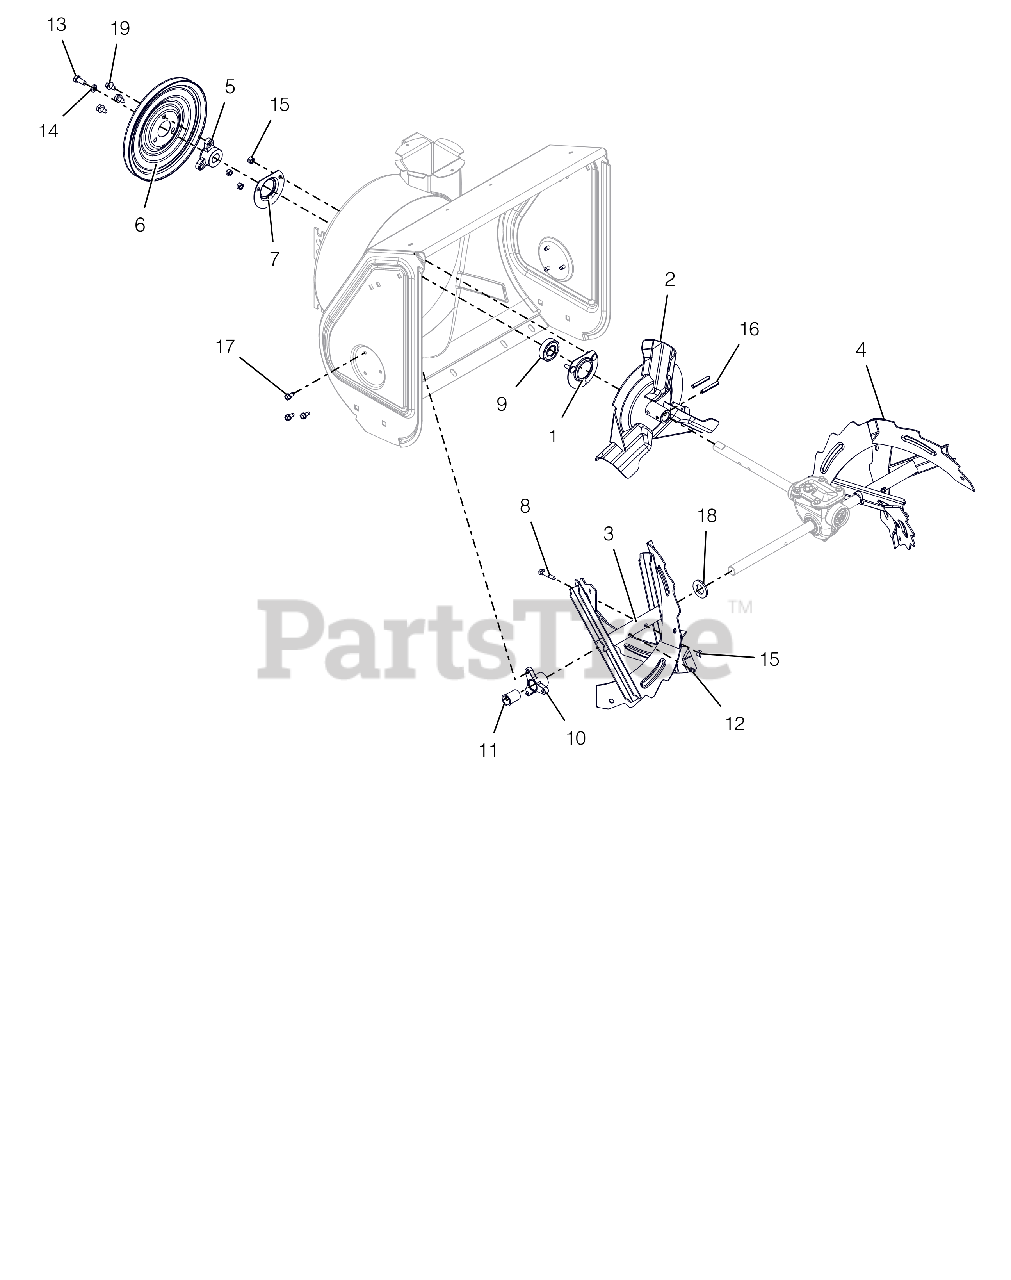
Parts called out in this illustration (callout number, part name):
1	BEARING FLANGE
2	IMPELLER, COMPACT 12" 3-BLADE
3	AUGER, 20" RH, BLK SERR W/ZERK
4	AUGER, LH 20", BLK SERR W/ZERK
5	PULLEY HUB, BOLT-ON D-BORE .75
6	PULLEY,SPIN FORM SINGLE GROOVE
7	BEARING FLANGE
8	SHEAR BOLT
9	BRG-BALL .750X1.750X.50
10	BUSHING, RAKE SHAFT .75"
11	BSHG-FLG SPLIT NYLINER .75"ID
12	ZERK,FITTING .25X.125 DRIVE IN
13	BLT-HEX .31-24X.75 YWZC GR5
14	WSHR-LK .312X.097 HVY YWZC
15	@NUT-LK-CTR .25-20 YWZC
16	PIN-ROLL .250X1.75
17	SCR-TAP .25-20X.50 HWH TR YWZ
18	@WSHR-FL-STL.812X1.50X.135YWZC
19	@SCR-TAP .31-18X.50 HWH TR YWZ
